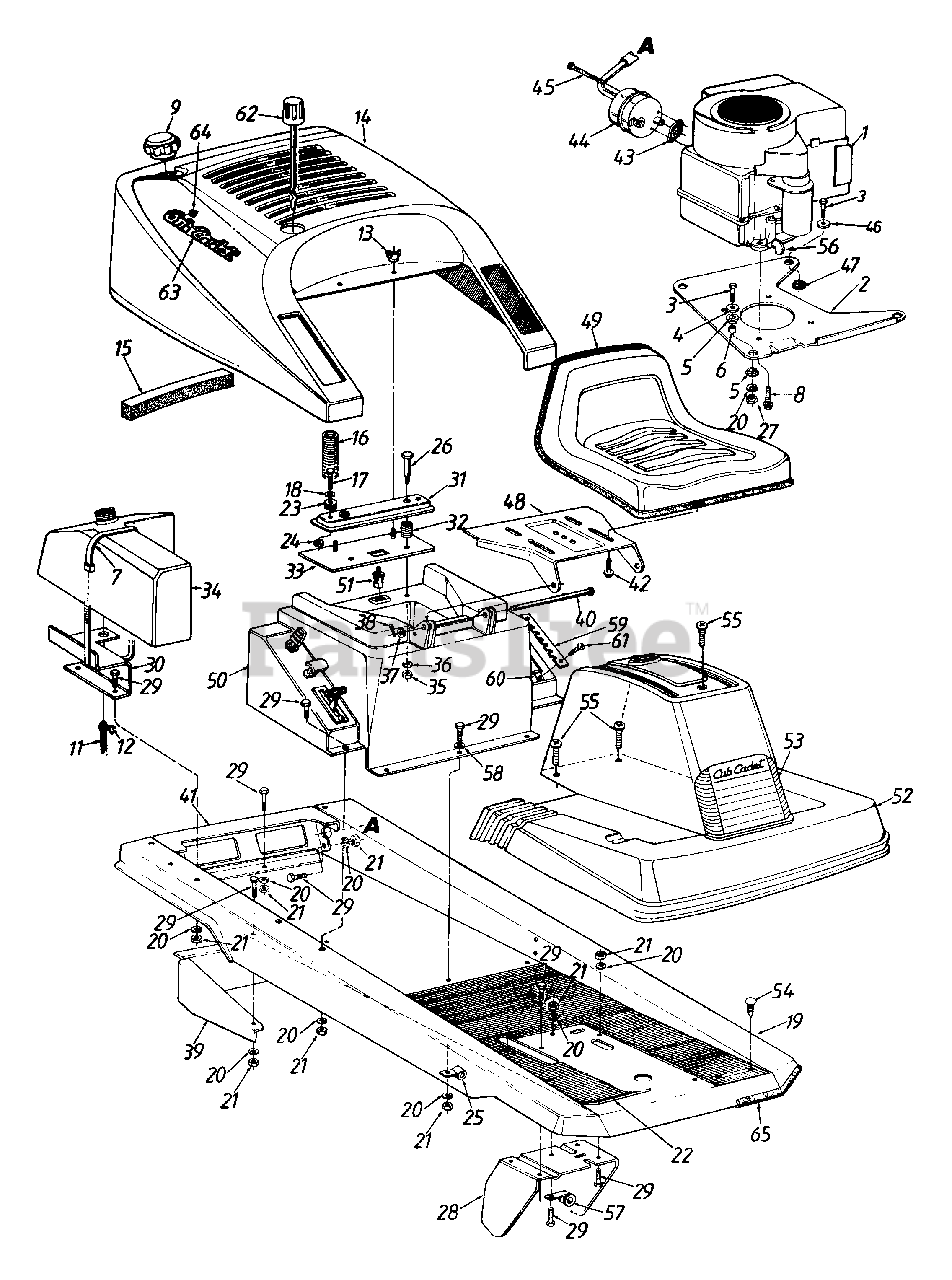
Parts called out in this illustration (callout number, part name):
1	Engine
4	FI-Wash..33" I.D. x 1.125" O.D.
5	Engine Mounting Grommet
6	Spacer.315" I.D. x.5" O.D.
7	Cable Tie 30.6" Lg.
8	Hex Wash. Hd. Self-Tap Scr. 3/8-16 x 1.25" Lg.
11	Gas Line - 15" Lg.
12	Hose Clamp
13	Wing Nut 1/4-20 Thd.
14	Rear Engine Cover
15	Foam Strip - 2 Req'd.
16	Compression Spring
17	Hex Bolt 5/16-18 x 7/8" Lg. (Gr. 5)
18	FI-Wash..344" I.D. x .875"
21	Hex Nut 5/16-18 Thd.
23	Elastemer Bushing
24	Hex Cent. L-Nut 5/16-18 Thd. (Gr. 5)
26	Shld. Bolt .5" Dia. x .84
27	Hex Nut 5/16-24 Thd.
35	Hex Nut 3/8-16 Thd.
36	L-Wash. 3/8" I.D.
37	Fl-Wash. 469" I.D. x 88" O.D.
38	Cotter Pin 3/32" Dia x 1.0" Lg.
43	Exhaust Gasket
45	Shld. Bolt 7/16" Dia x 3-5/8"
46	Fl-Wash. 33" I D. x 1.125" O.D.
47	Flange Washer .32" I D x .5"
52	Front Console
53	Headlight Lens
54	Ratchet Fastener .25" Dia. x .75" Lg
55	Pan Hd. Tap Scr #12 x .5" Lg.
56	90 deg. Elbow Male to Female
57	Cable Clip
58	Fl-Wash. 34" I.D. x .68" O.D.
59	Lift Reinforcement
60	Speed Nut #10-24 Thd.
61	Fl-Counter Sunk Scr #10-24 x 1.5" Lg
62	Oil Fill Extension
63	Logo
64	Push Nut
65	Trim Strip (39" Req'd.)
